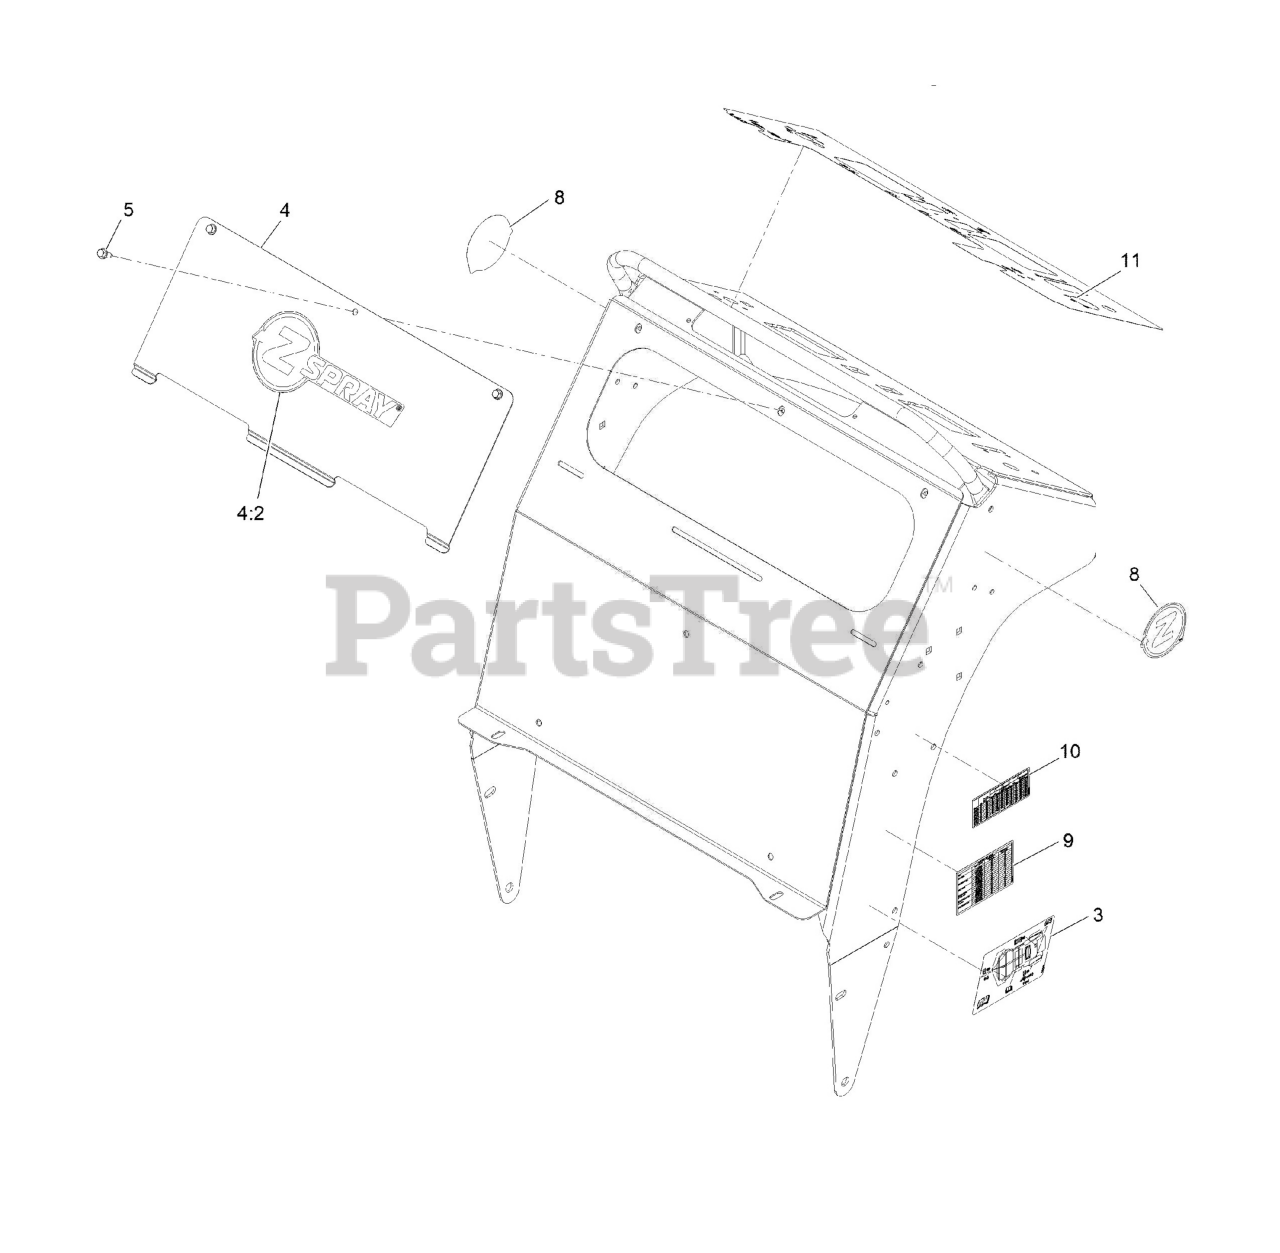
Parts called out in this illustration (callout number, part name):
3	DECAL-SERVICE AID
4	ACCESS PANEL W/ DECAL
4:2	Decal-Z-Spray
5	SCREW-HWH
8	Decal-Z-Logo
9	Decal-Spread Chart
10	Decal-Spray Chart
11	Decal-Control
